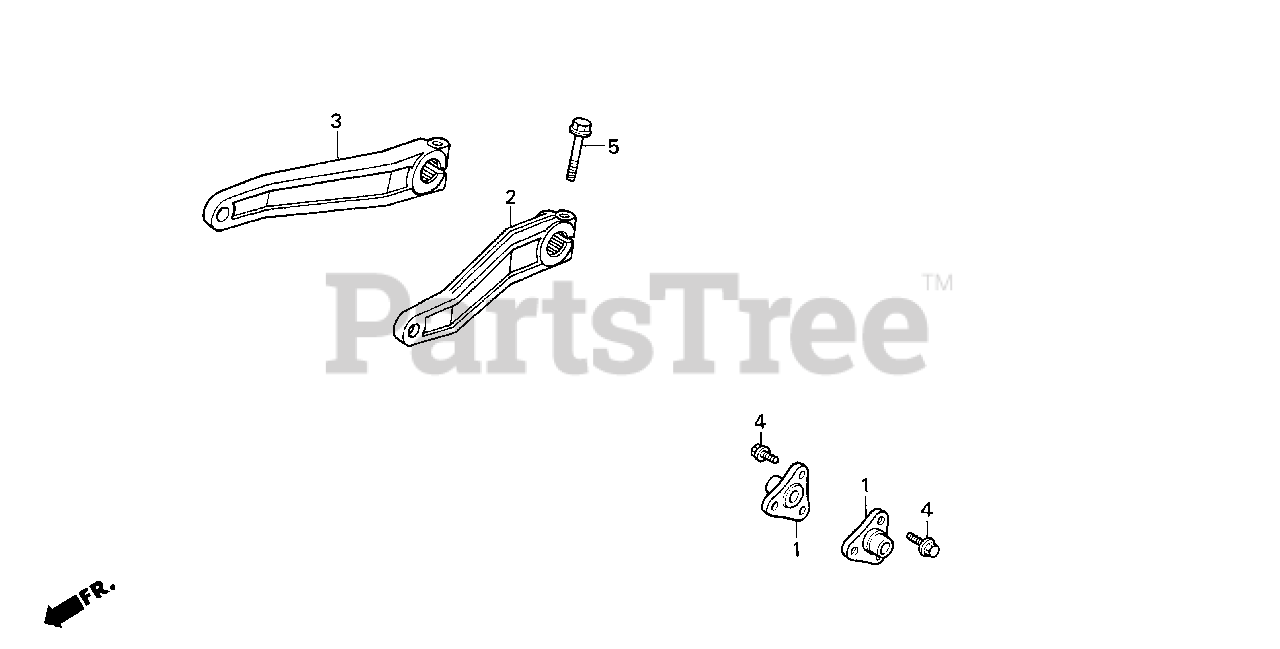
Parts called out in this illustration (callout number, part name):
1	PIVOT, FR. HITCH
2	ARM, L. FR. LIFT
3	ARM, R. FR. LIFT
4	BOLT, FLANGE (8X20)
5	BOLT, FLANGE (10X40)
